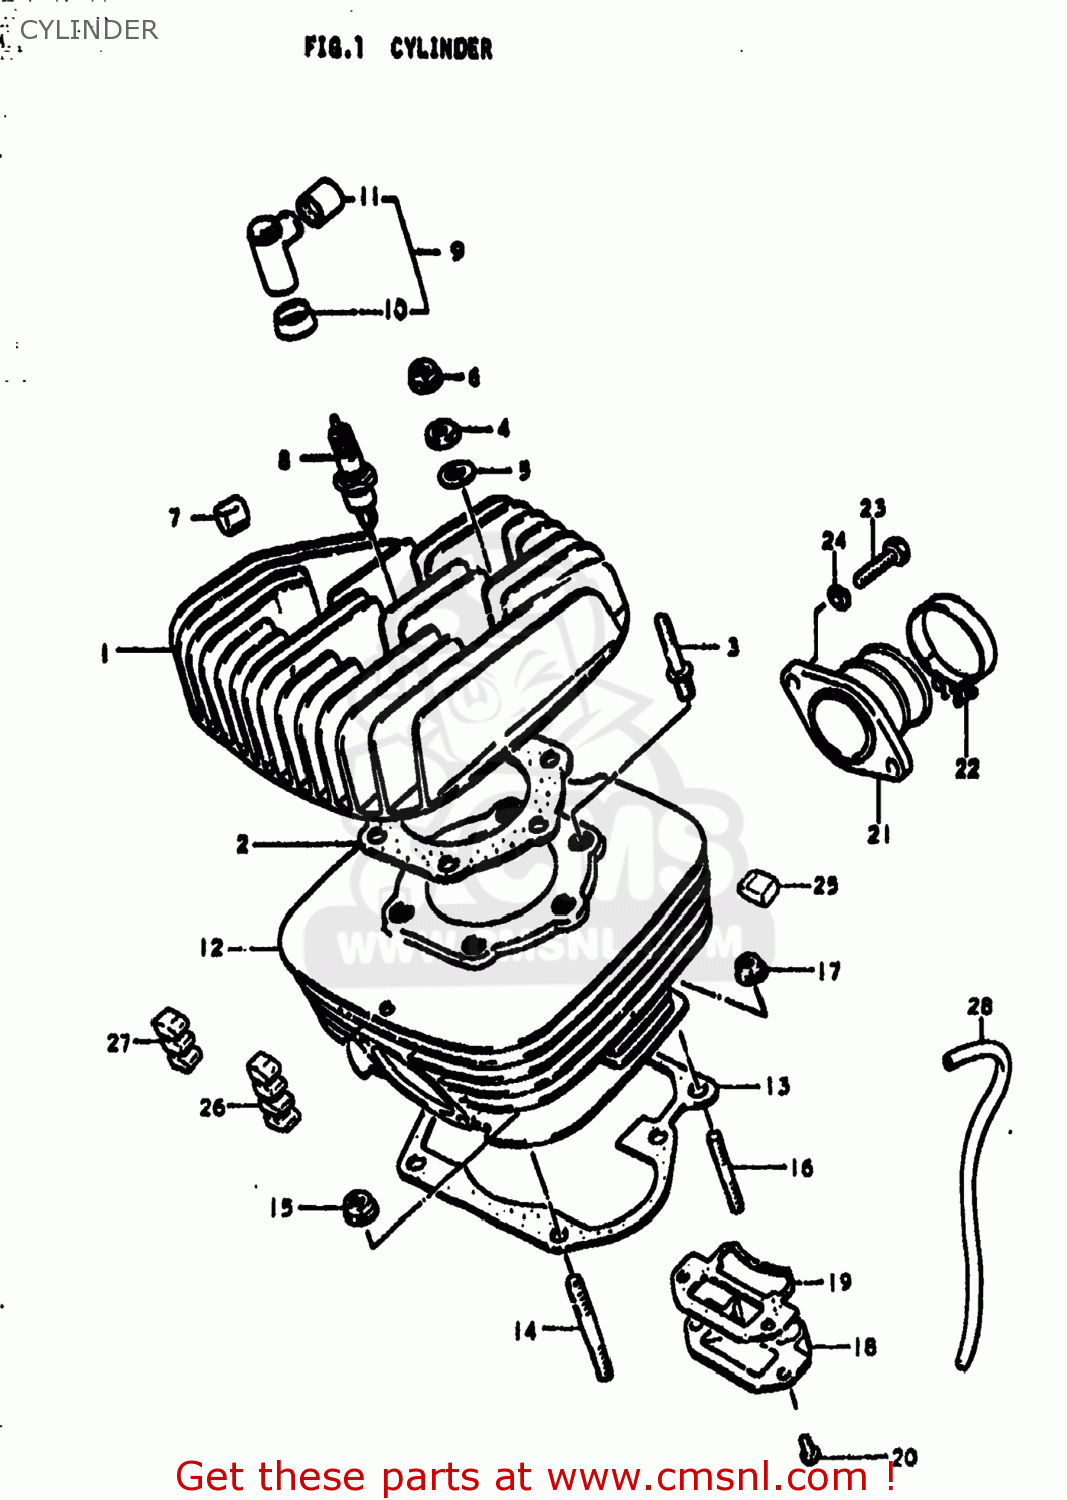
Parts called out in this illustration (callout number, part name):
1	HEAD,CYLINDER
2	GASKET,CYLINDER HEAD (MCA)
3	BOLT,STUD
4	NUT (8MM)
5	WASHER
6	NUT
7	PAD,CYLINDER
8	PLUG,SPARK(B7HS)
9	CAP,SPARK PLUG
10	SEAL,SPARK PLUG
11	SEAL,SPARK PLU
12	CYLINDER
13	GASKET,CYLINDER (MCA)
14	STUD 10X25
15	NUT
16	STUD 8X25
17	NUT
18	VALVE ASSY,REED
19	GASKET,REED VALVE (MCA)
20	SCREW
21	PIPE,INTAKE
22	CLAMP
23	BOLT
24	LOCK WASHER
25	PAD,CYLINDER
26	PAD,CYLINDER
27	PAD,CYLINDER
28	HOSE
